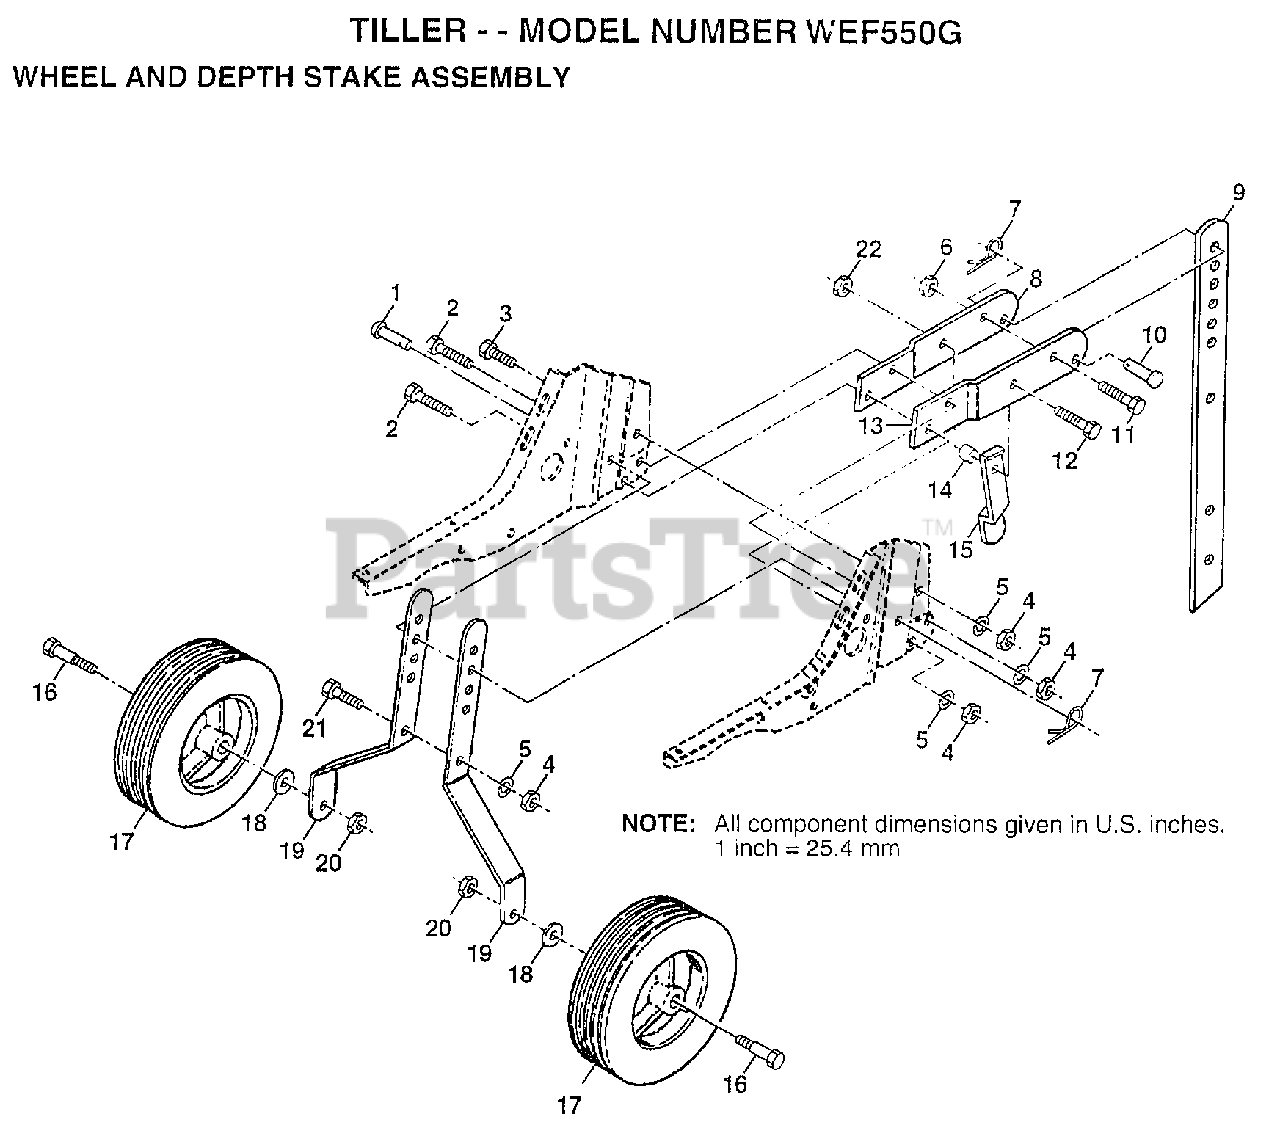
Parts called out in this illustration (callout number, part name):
1	DRILLED RIVET RT
3	BOLT
4	NUT.HEX.5/16-18
5	LOCKWASHER
6	NUT
7	SPRING.RETAINER
11	BOLT
12	BOLT.HEX.5/16-1.5
14	WASHER
15	STAKE SPRING TI
16	BOLT SHOULDER
17	WHEEL.8X1.75.YELL
18	WASHER
22	NUT
